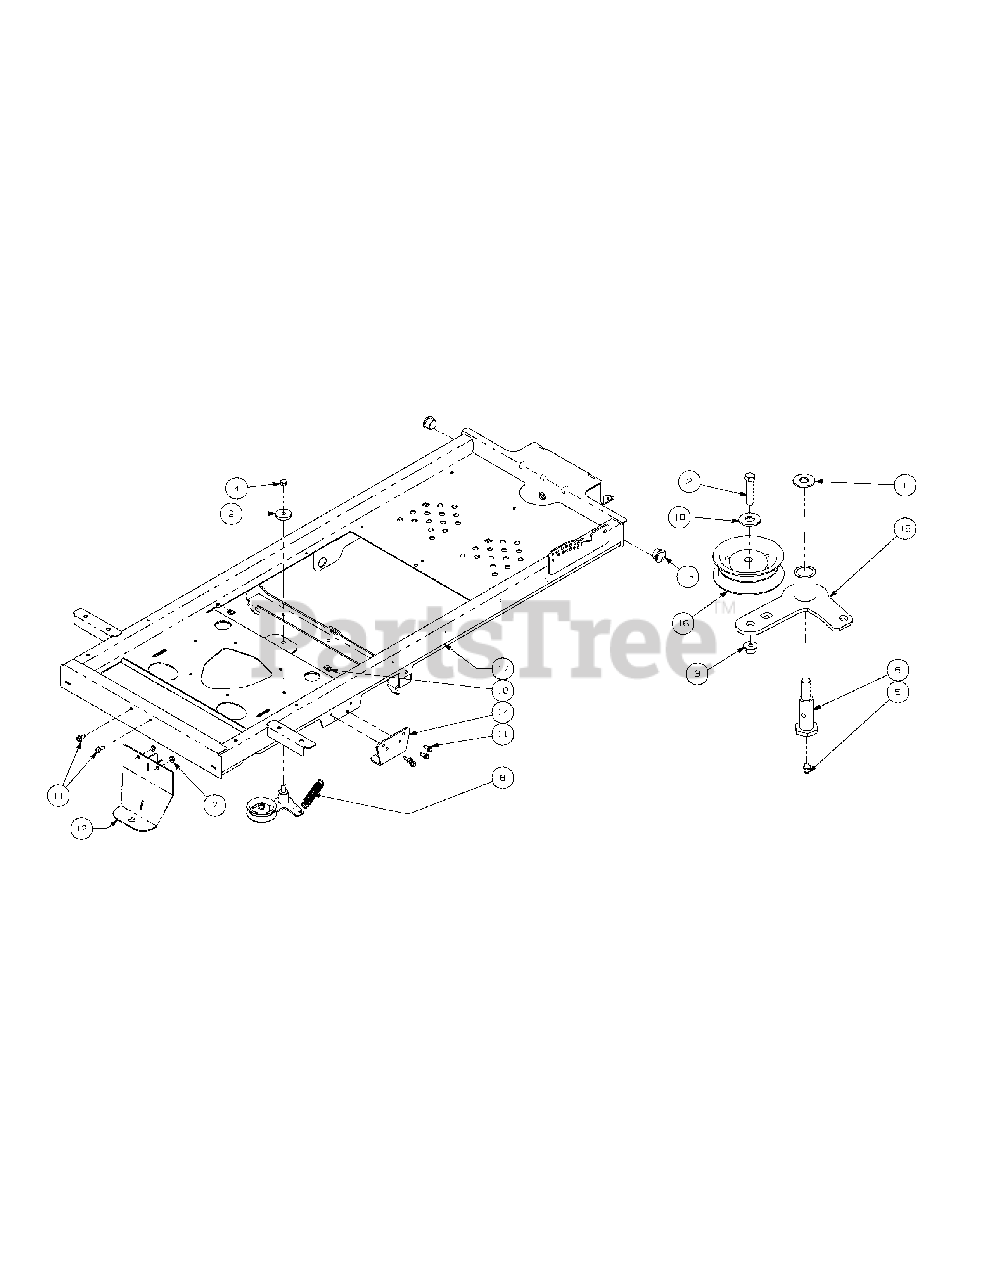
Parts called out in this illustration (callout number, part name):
1	Flat Washer, 3/8 zinc
2	Hex Cap Screw, 3/8-16 x 1-3/4
3	Hex Nut, 3/8-16 Flange Lock
4	Nylock Nut, 7/16-14
5	Grease Fitting, 1/4-28 x 3/16
6	Shoulder Bolt
7	Nut, 5/16-18, Hexflange Lock
8	Extension Spring, .865 OD x 4.68 lg
9	Flat Washer, 7/16 ID x 1.75 OD
10	U-Nut, 1/4-20
11	Self Tapping Screw 5/16-18 x .750
13	Bronze Bushing, 1.00 ID x 1.50 OD
14	Transmission Mounting Bracket
15	Idler Arm Assembly includes:
16	Flat Idler Pully w/ adaptor
17	Frame Assembly Weldment
18	Washer, 3/8, SS
